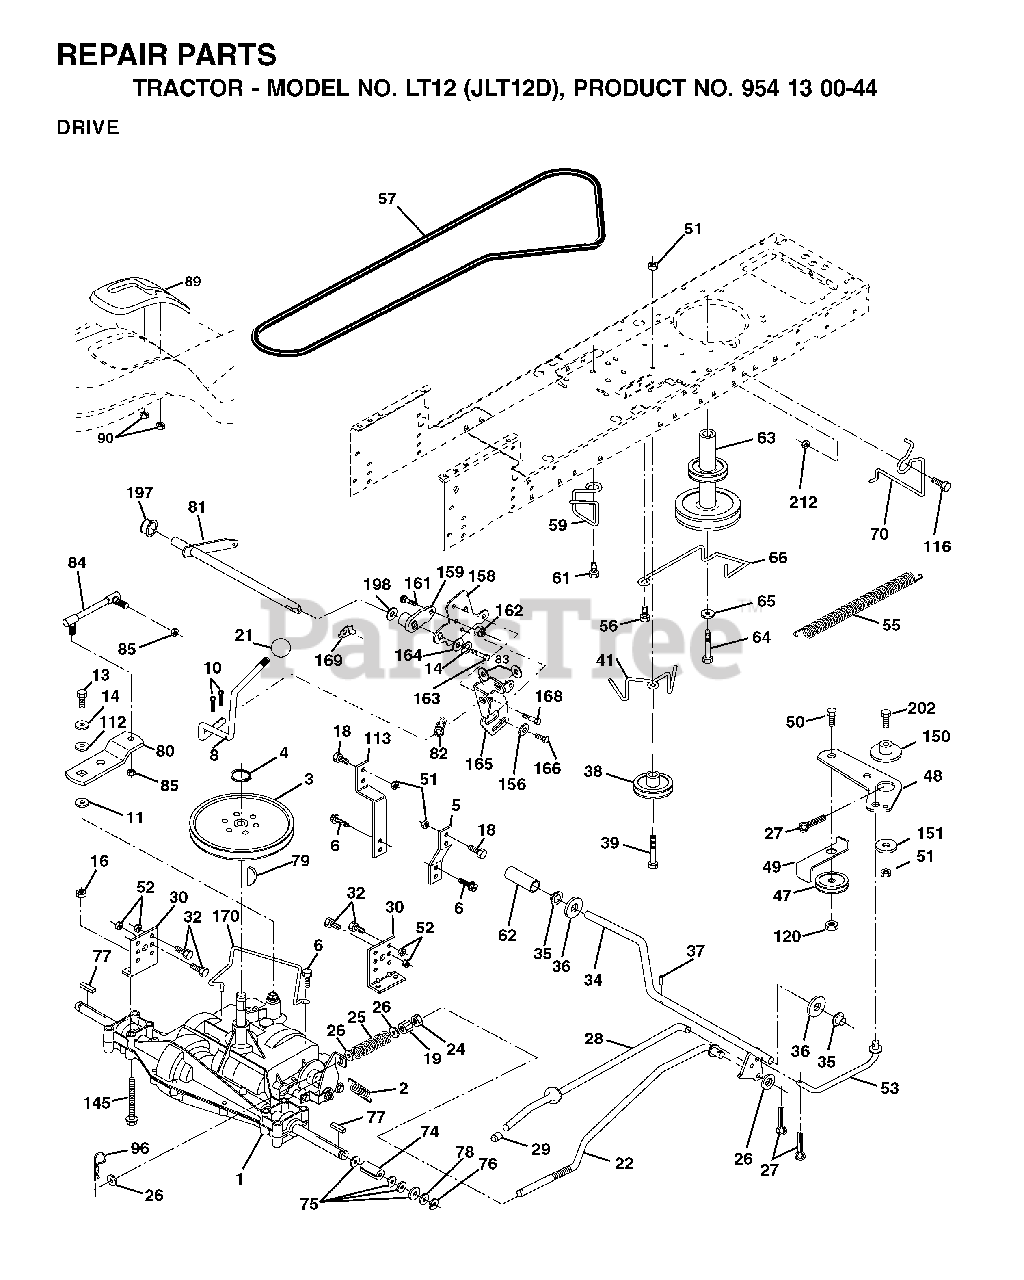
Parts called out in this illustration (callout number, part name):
2	SPRING,BRAKE RETURN
3	PULLEY TRANS
4	RETAINING RING LT
5	STRAP TORQUE
6	SCREW 5/16"
8	ROD SHIFT FENDER ADJUST STLT
10	PIN COTTER
11	WASH-SHFT PLT LT
13	BOLT 1/4-28X3/4
14	LOCKWASHER
16	NUT.71038.31-18.HEX.NYLOCK
19	NUT
21	KNOB.DUCKHEAD.1/2
22	ROD BRAKE
24	NUT
25	SPRING ROD LT
27	COTTER PIN
28	ROD, PARKING BRAKE
29	PLUNGER CAP
30	BRKT, MOUNT TRNSAXLE
32	BOLT
34	SHAFT, FOOT PEDAL
35	BEARING.NYLON
36	WASHER LT
37	DRIVE PIN
38	PULLEY IDLER COMPOSITE
39	BOLT
40	SPACER, SPLIT
41	KEEPER, BELT IDLER
42	WASHER
47	IDLER PULLEY
48	BELLCRANK, CLUTCH
49	RETAIN BELT
50	BOLT
51	LOCKNUT
52	LOCKNUT
53	LINK, CLUTCH LT
55	SPRING, RETURN LT
56	SCREW.3/8-16
57	V-BELT
59	KEEPER, BELT CENTER
61	SCREW 3/8-16X.875
62	PEDAL COVER T
63	ENGINE PULLEY
64	BOLT
65	LOCKWASHER
66	KEEPER BELT ENGINE
70	KEEPER BELT ENG
74	SPACER AXLE
76	E-RING LT
77	SQUARE KEY
80	ARM SHIFT
82	SHIFT SPRING
83	WASHER
85	NUT LOCK CENTER 1/4 -28 FNTHD
96	RETAINER M
112	WASHER LT
113	STRAP TORQUE LH LT
116	BOLT D
120	NUT LOCK FLG 3/8-16 UNC
150	SPACER, RETAINER
151	WASHER 12/32X2X10GA
156	WASHER.SRRTD.5/16
158	BRACKET
159	HUB
161	BOLT
162	NUT.CROWNLOCK.1/4
165	RP BRACKET
168	BOLT.SHOULDER.5/16-18X
169	PLATE.FASTENING.CROSS.SHAFT
170	KEEPER BELT T/A
197	NYLINER SNAP 5/8" ID
198	WASHER.NYL.7/8IDX.105"HYD CR
202	BOLT
212	NUT
